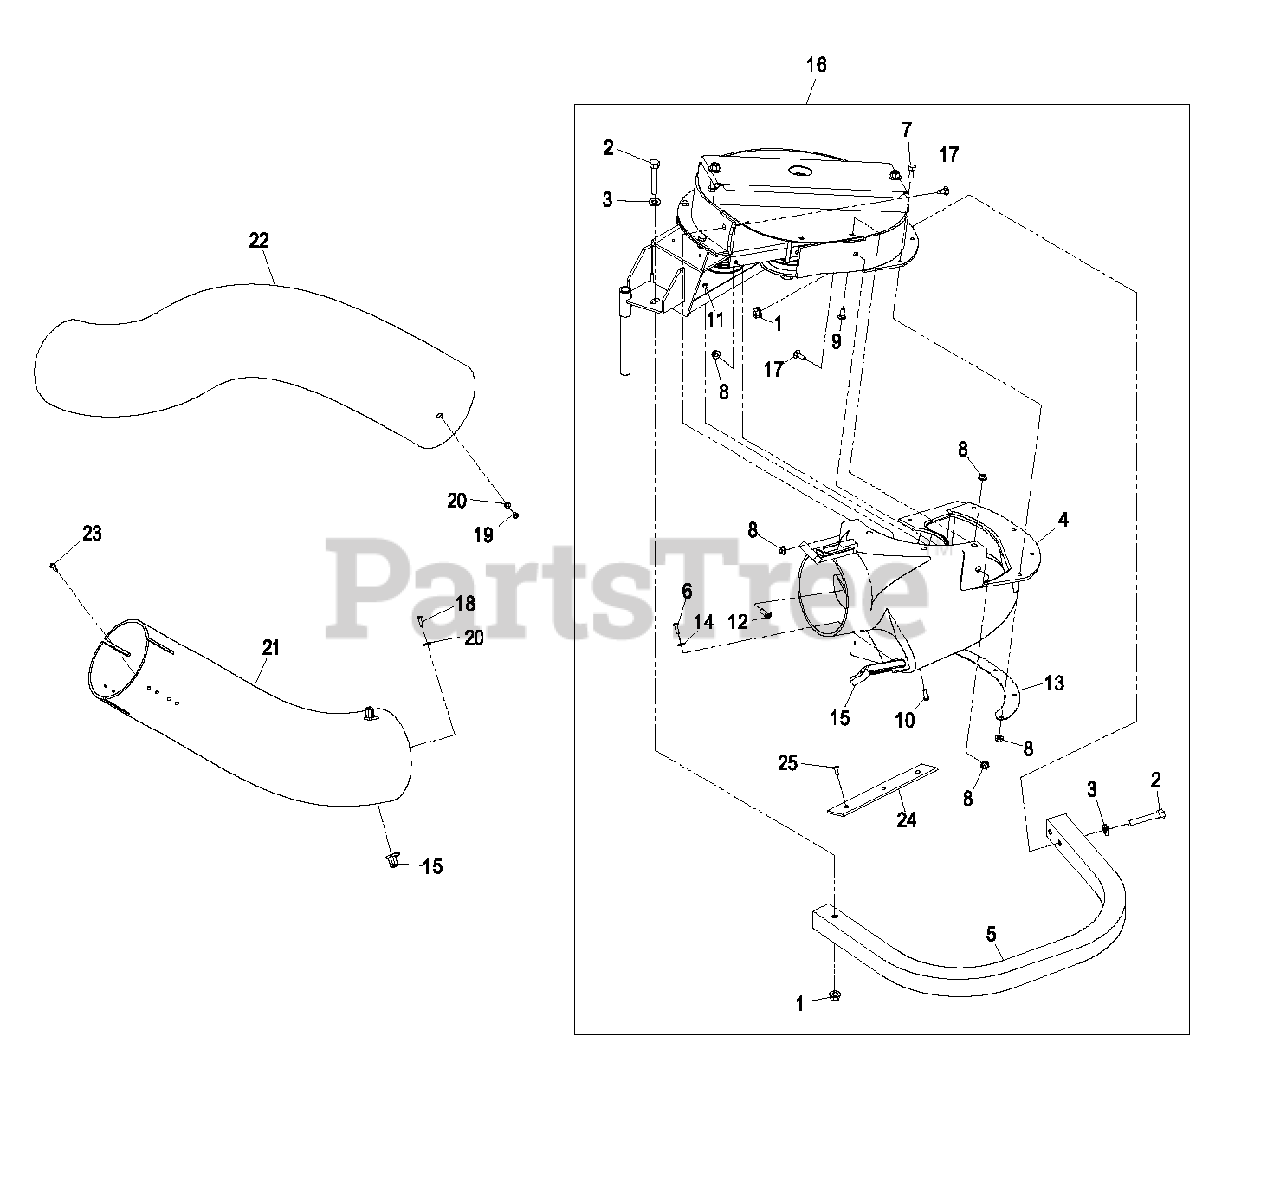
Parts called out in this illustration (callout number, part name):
1	NUT-HHF, WHIZ
2	SCREW-HH
3	WASHER-FLAT
4	ASM,BLOWER CHUTE SMALL
6	SCREW-PPH
7	SCREW-HH
9	SCREW-CARR
10	SCREW-HEAD, TRUSS
13	PLATE-BACKING, BLOWER
14	WASHER-FLAT
15	LATCH DRAW
16	ASM,BLOWER 44/48 - SERVIC
17	BOLT-CARR
18	SCREW-PPH
19	NUT-LOCK, NI
20	WASHER-FLAT
21	KIT,LOWER TUBE
22	TUBE,UPPER 44/48
23	SCREW-HWH
24	PLATE-REINFORCEMENT
25	RIVET-BLIND
